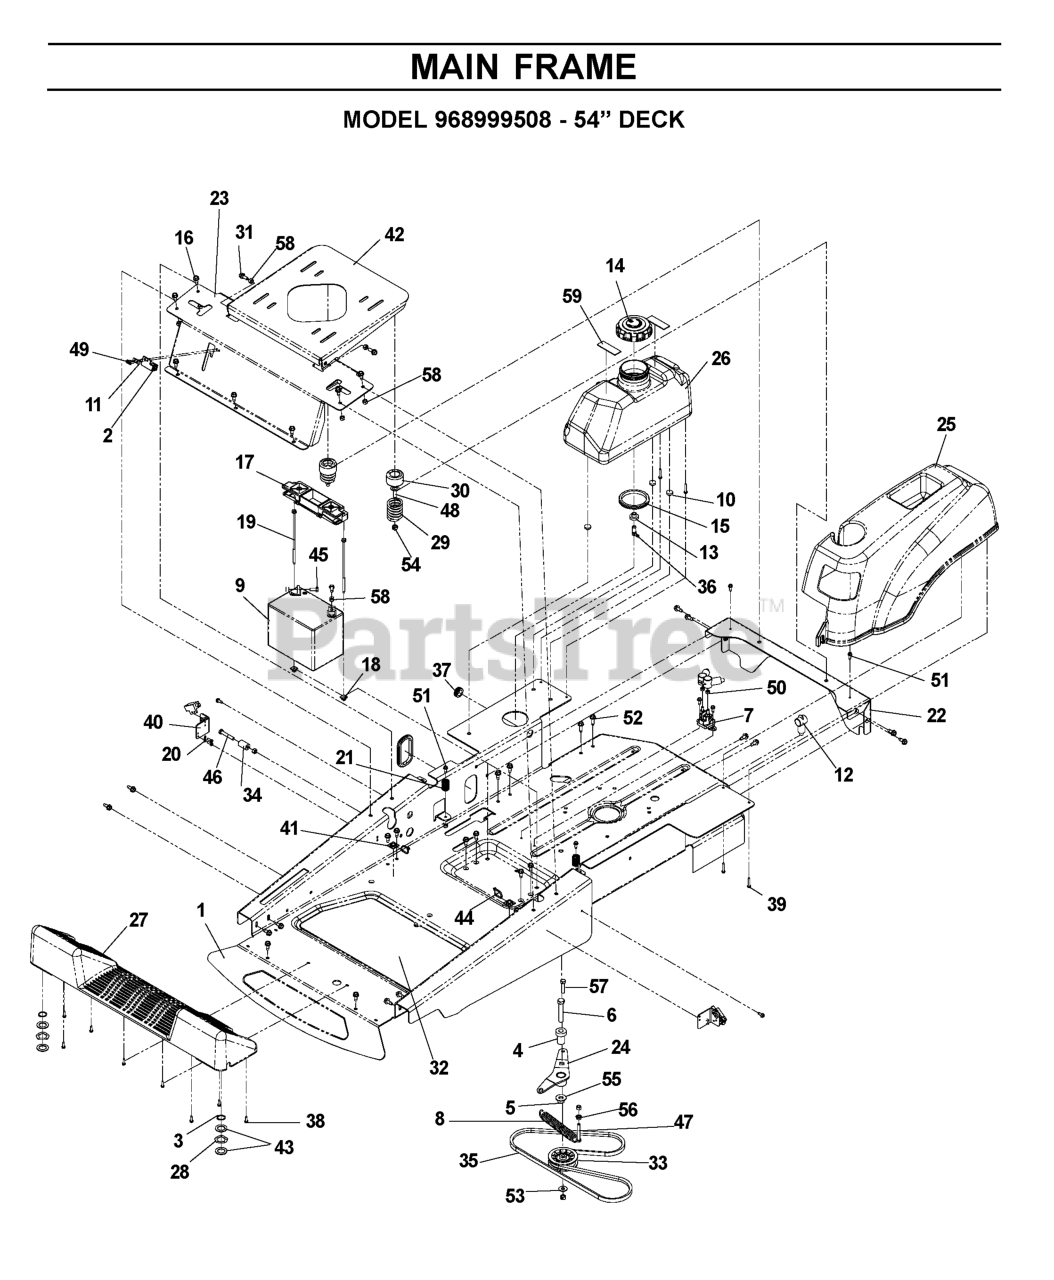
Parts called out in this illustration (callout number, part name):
1	CHASSIS W/DECALS
2	SWITCH, INTERLOCK
3	RETAINING RING, 7/8"
4	IDLER SPINDLE
5	NUT 1/2-13 HEX NYLOC ZD
6	HCS 1/2C X 2 3/4
9	BATTERY, 12 V 330 AMP
10	GROMMET, BUMPER
11	TAPPED PLATE
13	RUBBER GROMMET
14	FUEL CAP ANTI-SPLASH
16	BOLT 5/16-18 X 3/4
17	BATTERY HOLD DOWN
18	PUSH NUT-NYLON
19	BOLT - 1/4-20 X 7.5
20	WASHER - 3/16 LOCK ZD
21	SPRING, RETURN TO NEUTRAL
22	REAR SEAT SUPPORT ORANGE
23	CONSOLE
24	PUMP IDLER WELDMENT
25	FENDER LEFT
27	FOOT REST GRAY
29	SPRING, SEAT
30	CAP, SPRING COVER
31	BOLT, SHOULDER
32	SLIP, MATTING
37	GROMMET, FUEL LINE
38	SCR #10-12X3/4 HEX WAS HD ZD
39	SCR #10-12X1-1/2HEX WASH HD ZD
41	MOUNTING BLOCK CABLE TIE
42	SEAT MOUNT, BLACK
43	BSHG .875 X 1.375 X .074 ZD
44	TIE, PLASTIC
45	HCS 5/16C X 3/4
46	HCS 5/16-18X2
48	HCS 3/8C X 1 1/4 GR5
49	SCREW #10-24 X 5/8
50	NUT.1/4-20.HEX.NYLOC.ZD
53	WASHER 3/8 FLAT
54	NUT 3/8C CENTERBLOCK
55	WASHER 1/2 FLAT
56	NUT 5/16C WHIZ
57	HCS 3/8C X 1 1/2
58	NUT 5/16 NYLOC
59	FOAM STRIP, FUEL TANK
